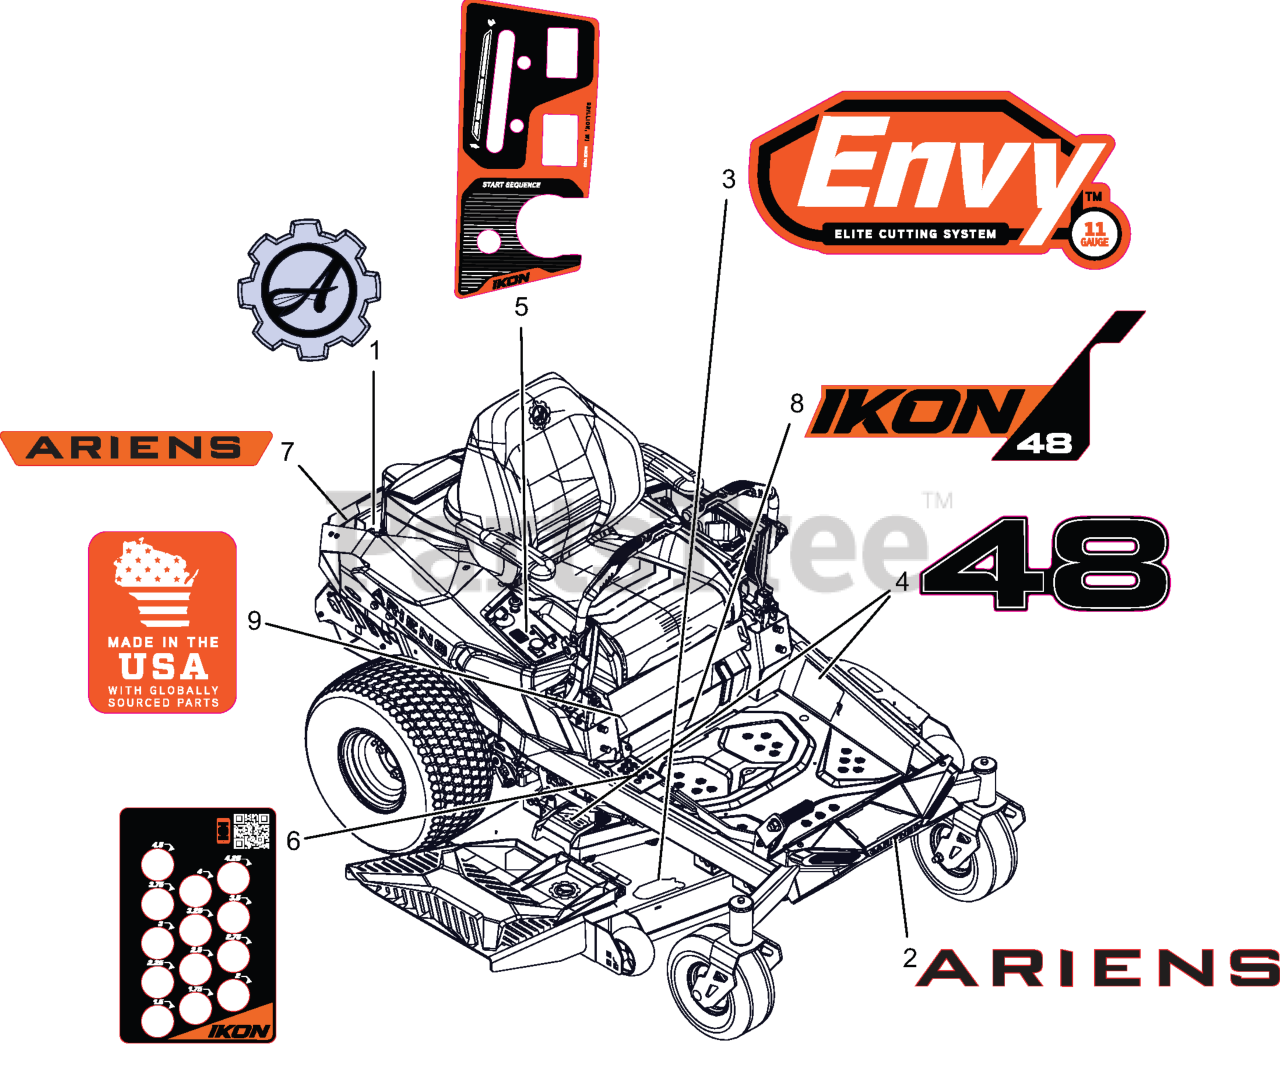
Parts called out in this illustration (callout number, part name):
1	DECAL- ARIENS GEAR BADGE
2	DECAL- ARIENS-BADGE
3	DECAL- DECK
4	DECAL- 48
5	DECAL- CONTROL PANEL
6	DECAL- HEIGHT OF CUT
7	DECAL- ARIENS
8	DECAL- IKON 48 KICKPLATE
9	DECAL- MADE IN USA
